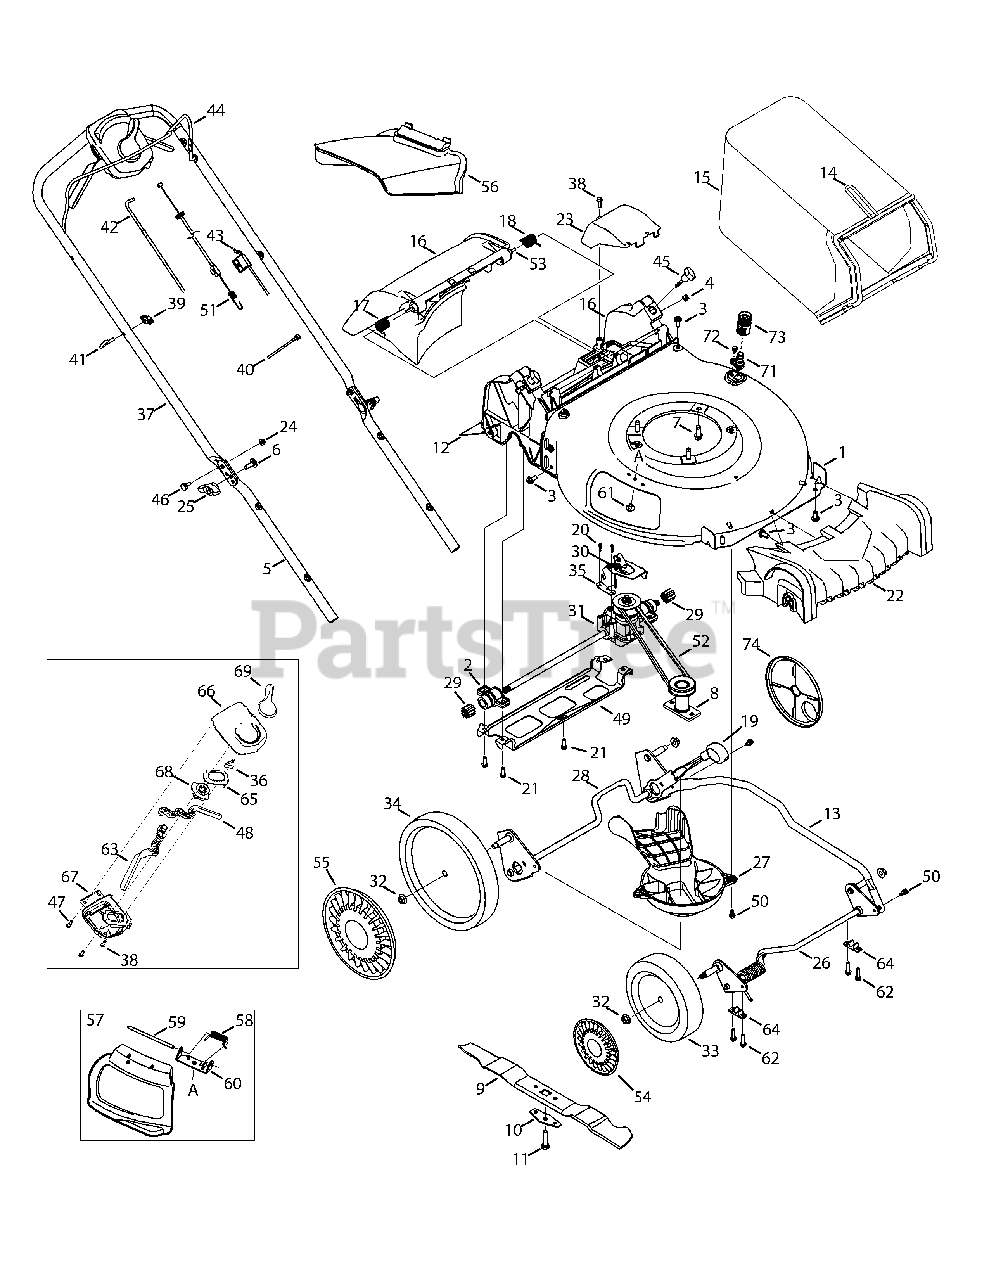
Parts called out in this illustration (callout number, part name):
1	Deck, 21" w/ deck wash
2	Bearing Assembly
3	Screw, 5/16-14 x .750
4	Nut, Sq., 1/4-20
5	Lower Handle
6	Carriage Screw, 5/16-18
7	Screw, 3/8-16 x 1.00
8	Blade Adapter
9	Mulching Blade
10	Blade Bell Support
11	Screw, 3/8-24 x 1.50
12	Trailing Shield
14	Grass Catcher Frame
15	Grass Bag
16	Rear Discharge Door Assembly
17	Torsion Spring - RH
18	Torsion Spring - LH
19	Adjustment Lever Knob, Red
20	Screw, .159 x .43 Hex Washer
21	Screw, 1/4-15 x 1.25
22	Front Cover
23	Transmission Cover
24	Nut, Flange Lock, 1/4-20
25	Wing Knob
26	Front Axle Assembly
27	Engine Baffle
28	Rear Axle Assembly
29	Spur Gear, 9T
30	Exten. Spring, 2.675
31	Transmission Assembly
32	Flange Lock Nut, 3/8-16
33	Front Wheel
34	Rear Wheel
35	Transmission Bracket
36	Spring
37	Upper Handle
38	Screw, 1/4-15 x .750
40	Cable Tie
41	Rope Guide
42	Drive Cable
43	Control Cable (Kohler)
44	Blade Control
45	Wing Nut
46	Shoulder Screw, .375 x .126 x 1/4-20
47	Shoulder Screw, 1/4-15 x .970
48	Control Lever LH
49	Rear Support Bracket
50	Shoulder Screw, 1/4-20 x .50
51	Speed Adjustment Cable
52	V-Belt
53	Pivot Rod
54	Hubcap, Grey
55	Hubcap, 11", Grey
56	Side Discharge Chute
57	Mulch Plug (Incl. 58-60)
58	Torsion Spring
59	Hinge Pin
60	Chute Deflector Bracket
61	Screw, 1/4-20 x .500
62	Screw, 1/4-15 x 1.000
63	Control Lever RH
64	Bushing, Lock, .505 Dia. X .62
65	Cable Adjust Plate
66	Upper Housing
67	Lower Housing
68	Speed Adjust Actuator
69	Speed Select Lever
71	Water Nozzle
72	Shoulder Screw, 1/4-20 x .50
73	Water Nozzle Adapter
74	Wheel Dust Cover
